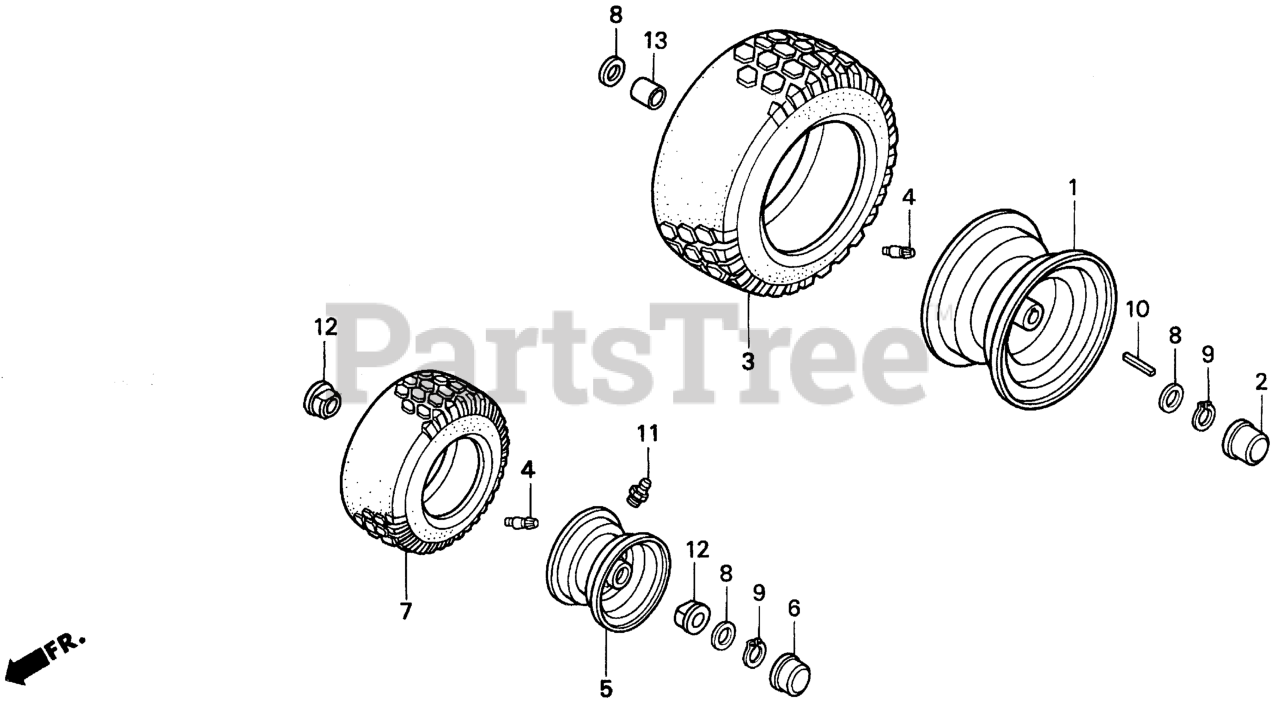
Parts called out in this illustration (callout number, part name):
1	WHEEL, RR.
2	CAP, RR. WHEEL
3	TIRE (18X8.5-8) (TURF)
4	VALVE (TR-412)
5	WHEEL, FR.
6	CAP, FR. WHEEL
7	TIRE (13X6.5-6) (TURF)
8	PLATE, PILLION STEP SIDE
9	CIRCLIP, EX. (3/4")
10	KEY (3/16")
11	NIPPLE, GREASE
12	BEARING, FR. WHEEL
13	COLLAR (25.4X2.3X28.5)
